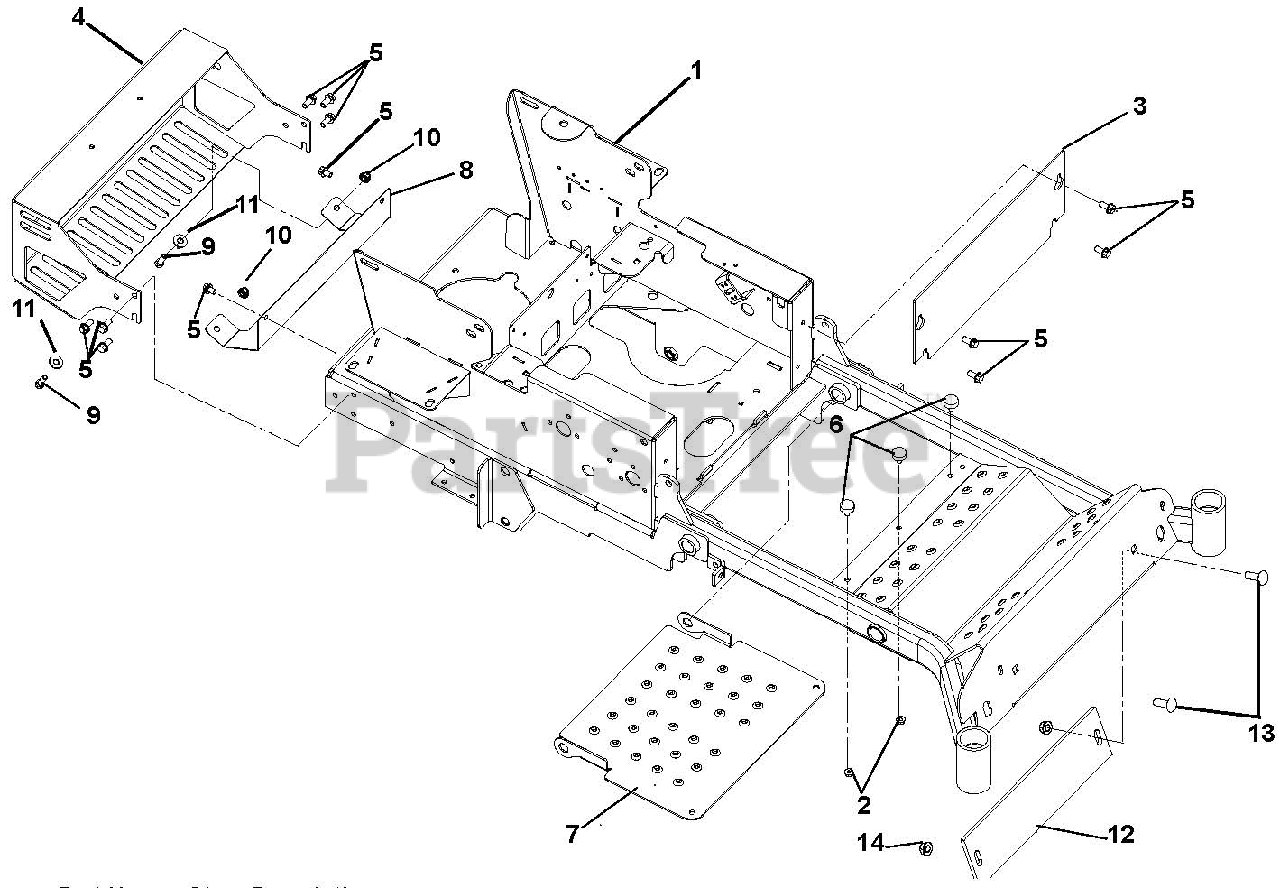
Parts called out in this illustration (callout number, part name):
1	Zoom HD 52-60 Main Frame Weldment
1	ZT HD 44-48 Main Frame Weldment
2	Nut, Spin Lock Flange .312-18
3	Kick Plate
4	Weldment Gravely, CZ Bumper
5	Screw, Tapping .38-16 x .75 Hex Washer Head
6	Bumper, Rubber
7	Panel, Inspection
8	Heat Shield, Compact Z
9	Bolt, Hex .38-16 x 1.00 Grade 5
10	Nut, Nyloc Flange .38-16
11	Washer, Flat Steel .438 x 1.00 x .083
12	Counterwieght CZ Front- Red
13	Bolt, Round Head Square Neck .50-13 x 1.50 Grade 5
14	Nut .50-13 Nyloc Flange
